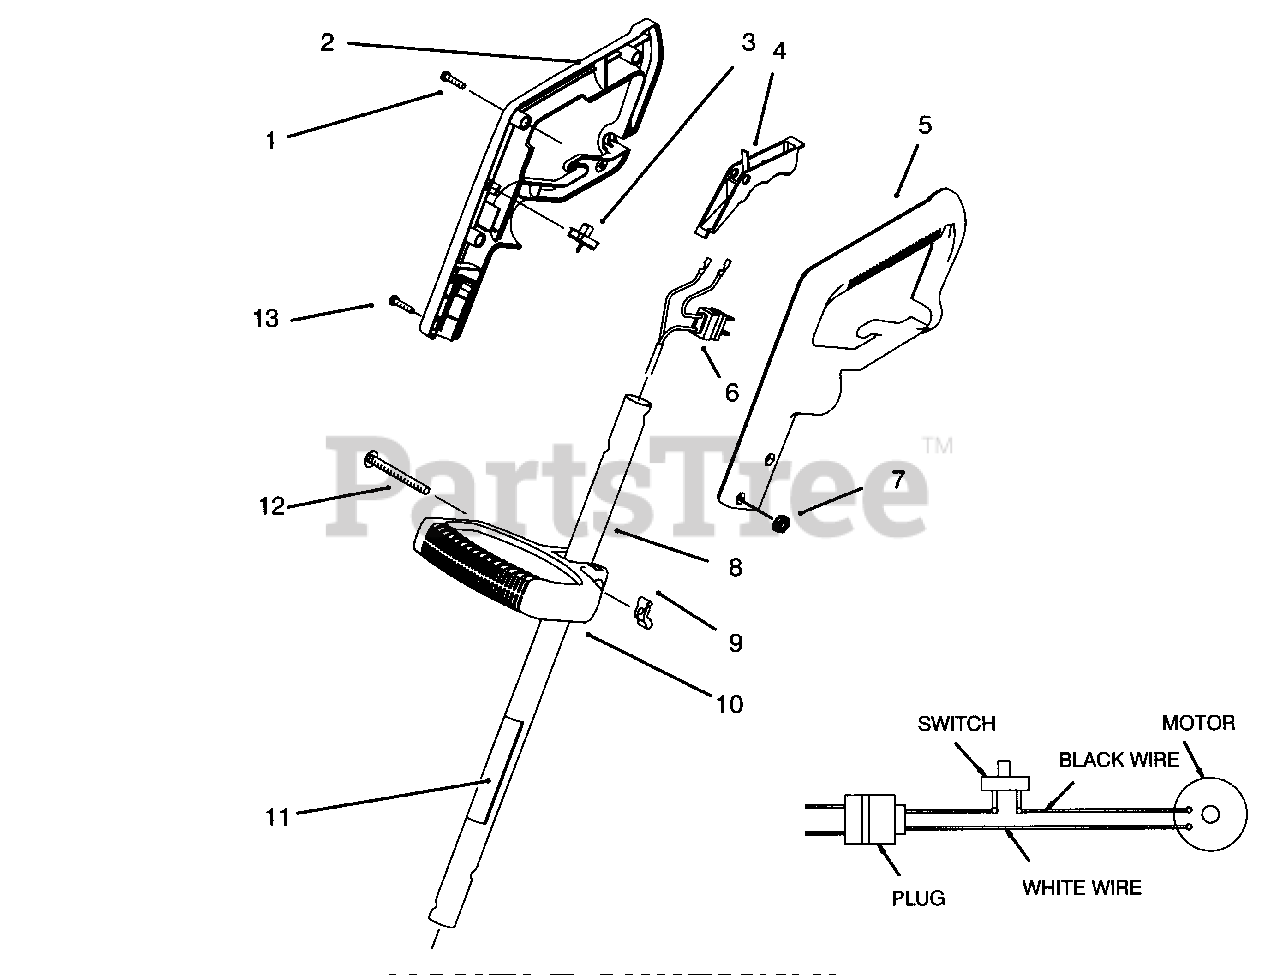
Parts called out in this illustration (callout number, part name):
1	Screw-Pan Hd. Tapping
2	Grip-Hand R.H.
3	Switch-Single Speed
5	Grip-Hand L.H.
6	Harness-Wire
7	Nut-Lock
8	Tube Assembly (Incl. Ref. #11)
10	Handle-Mid
11	Decal-Safety
12	Screw-Carriage
13	Screw-Pan Hd.
